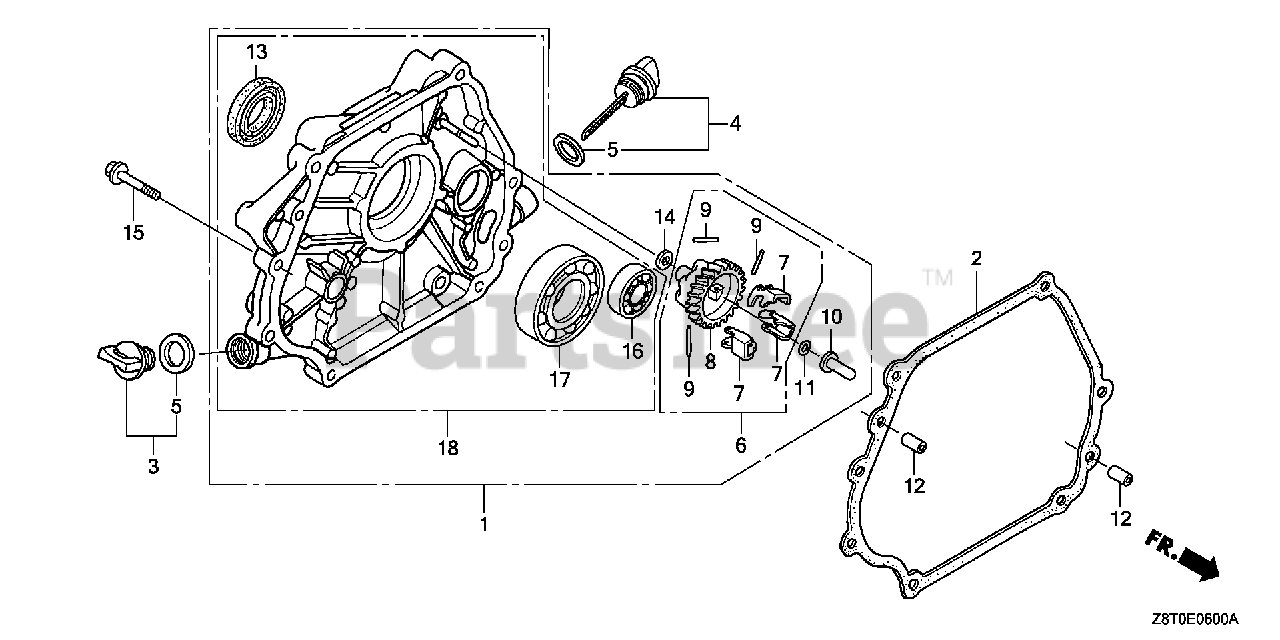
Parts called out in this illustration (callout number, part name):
1	COVER ASSY., CRANKCASE
2	GASKET, CRANKCASE COVER
3	CAP ASSY., OIL FILLER
4	CAP ASSY., OIL FILLER
5	GASKET, OIL FILLER CAP
6	GOVERNOR ASSY.
7	WEIGHT, GOVERNOR
8	HOLDER, GOVERNOR WEIGHT
9	PIN, GOVERNOR WEIGHT
10	SLIDER, GOVERNOR
11	CLIP, GOVERNOR HOLDER
12	PIN, DOWEL (8X12)
13	OIL SEAL (35X52X8) (NOK)
14	WASHER, PLAIN (6MM)
15	BOLT, FLANGE (8X40) Use up to Engine SN 1003236.
16	BEARING, RADIAL BALL (6202)
17	BEARING, RADIAL BALL (6207)
